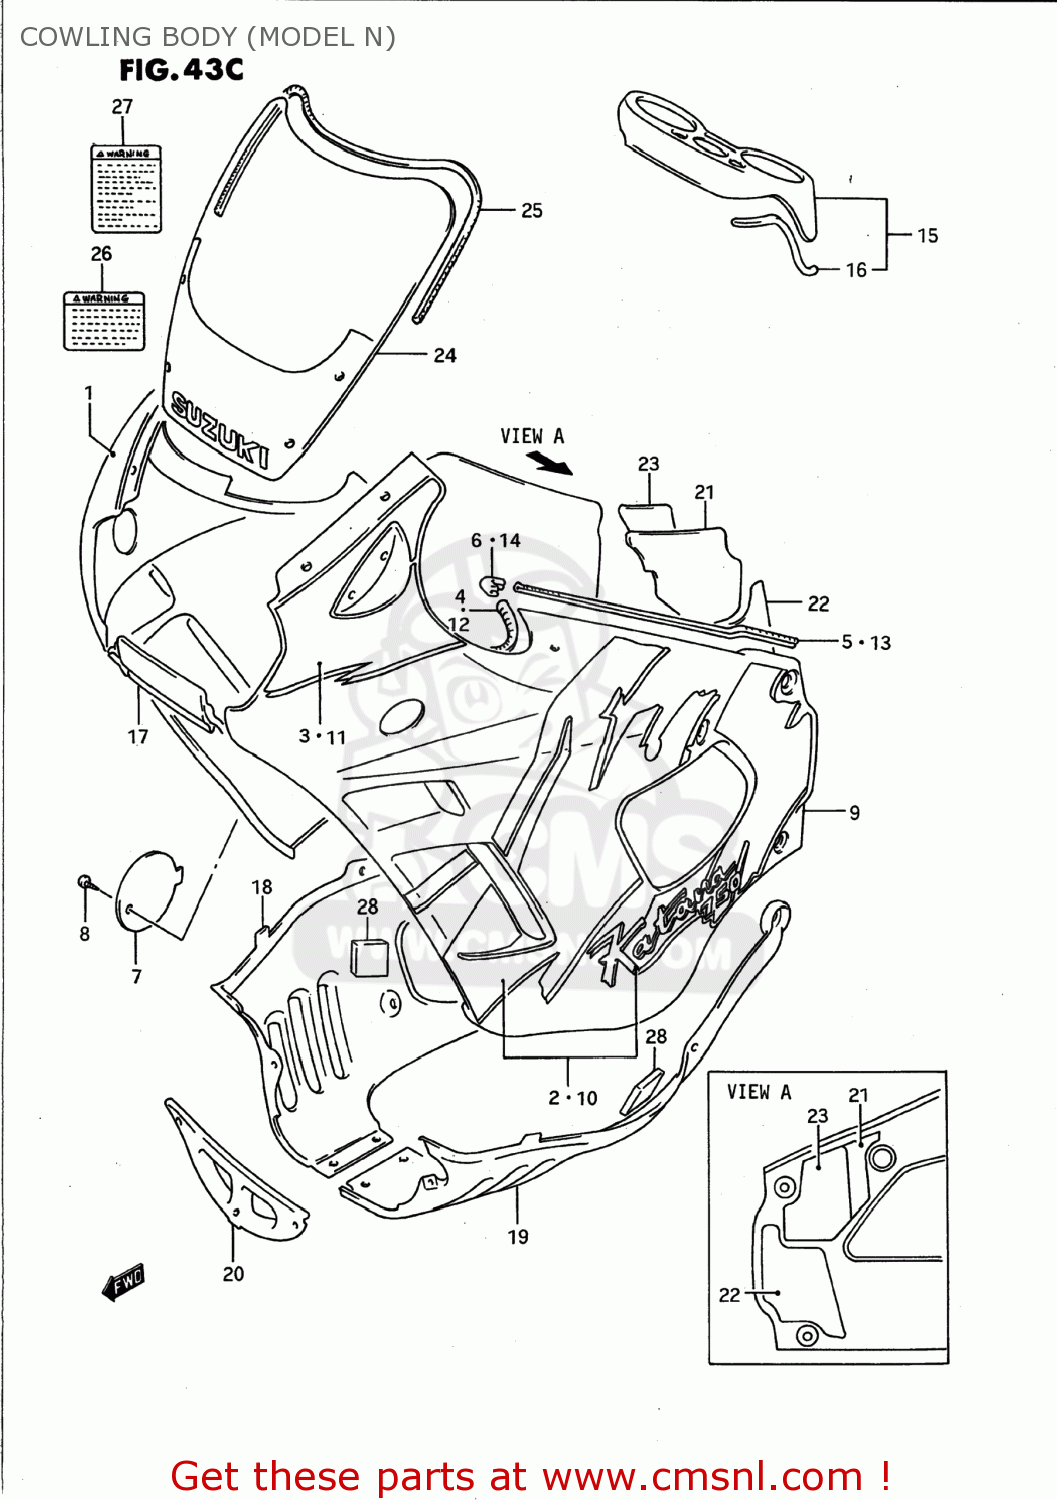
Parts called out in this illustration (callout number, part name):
1	COVER ASSEMBLY,COWLING,RIGHT
2	TAPE SET,BODY COWLING SIDE
3	TAPE,BODY COWLING SIDE,UPPER
3A	COVER,COWLING METER SIDE,R
3B	COVER,COWLING METER,SIDE
3C	SCREW
4	MOLDING
5	MOLDING
6	JOINT,MOLDING END
7	LID,OIL
8	SCREW(6X16)
9	COVER ASSEMBLY,COWLING,LEFT
10	TAPE SET,BODY COWLING SIDE
11	TAPE,BODY COWL SIDE UPR,L
11A	COVER,COWLING METER,SIDE
11B	COVER,COWLING METER SIDE,L
11C	SCREW
12	MOLDING
13	MOLDING
14	JOINT,MOLDING END
15	COVER COMP,METER
16	MOLDING
17	PANEL,COWLING CTR
18	COVER,COWLING UNDER,R
19	COVER,COWLING UNDER,L
20	COVER,COWLING UNDER FR
21	BALANCER SHEET,COWLING,R
22	SHEET,COWLING BALANCER
23	CUSHION,COWLING,R
24	WINDOW COMP,COWLING
25	MOLDING
26	LABEL
27	LABEL (WARNING SCREEN)
28	CUSHION,UNDER COWLING
29	LABEL (TIRE AIR PRESSURE)
30	LABEL (REAR SHOCK ABSORBER)
